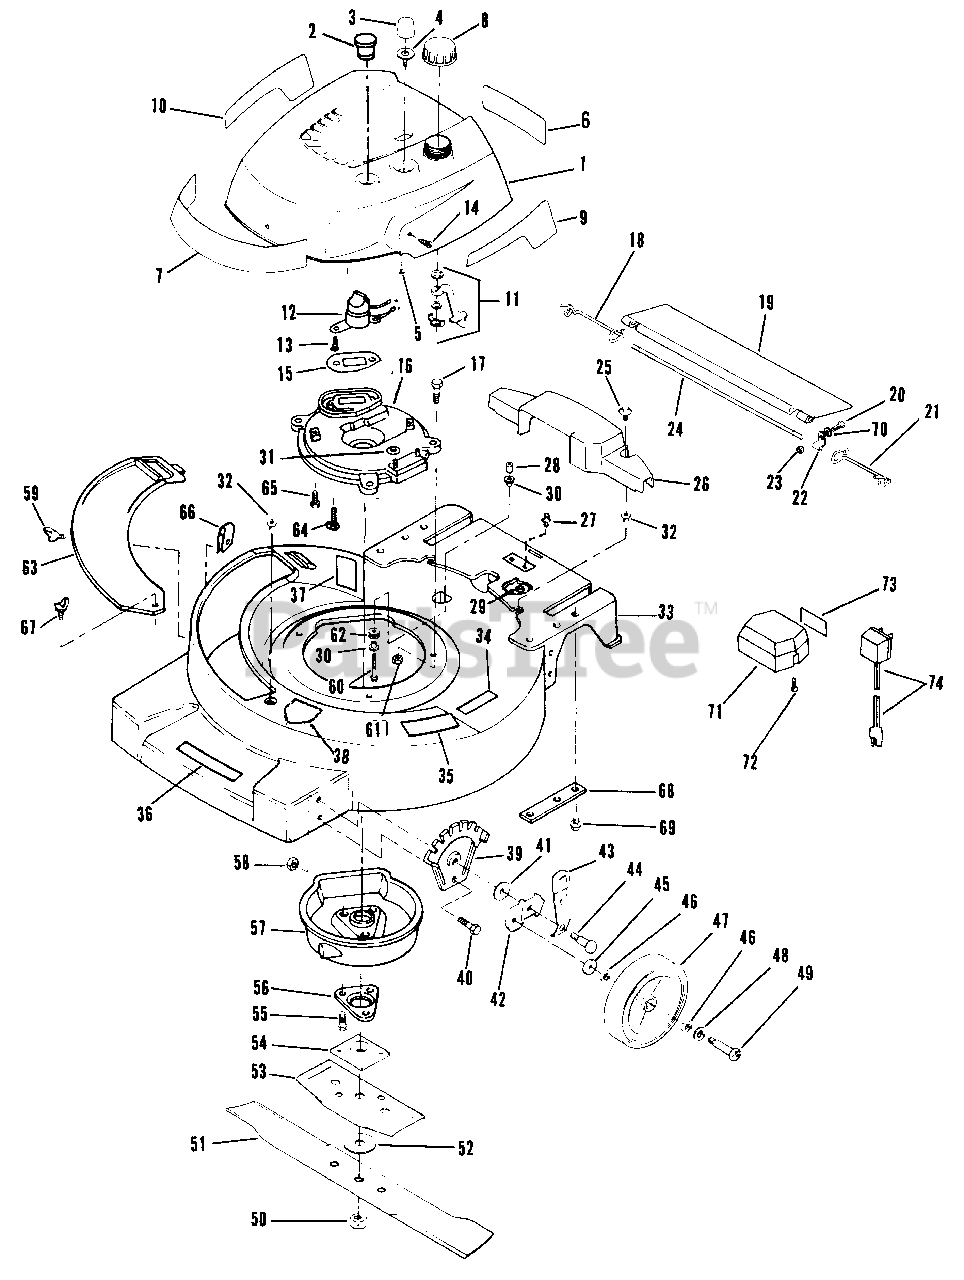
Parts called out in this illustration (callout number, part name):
1	Shroud-Engine
1	Shroud Assembly-8671AE Only
2	Plug
3	Bulb-Primer
4	Base-Primer
5	Nut
6	Decal-Instructions
7	Decal-Lawn-Boy
8	Fuel Cap
9	Decal-L.H.
10	Decal-R.H.
11	Fuel Shut-Off Assembly
12	Switch-On-Off
13	Screw
14	Screw-Shroud Mounting
15	Gasket-Exhaust
16	Plate-Muffler
17	Screw-Muffler Plate to Housing
18	Spring-R.H.
19	Shield-Trailing
20	Screw
21	Spring-L.H.
22	Clamp
23	Nut
24	Rod-Trailing Shield
25	Screw-Axle Cover Mounting
26	Cover-Drive Axle
27	Ball Stud, Battery Mounting
28	Spacer
29	Nut, Ball Stud
30	Spacer
31	Pushnut-Model Plate Mtg
32	Grommet
33	Housing Assembly
33	Housing Assembly-8671AE Only
34	Decal-Starting Pad
35	Pad-Starting
36	Decal-Caution
37	Decal-Discharge Area
38	Decal Blade Contact Warning
39	Plate-Height Adjust Backup
40	Screw-Height Adjust Plate
41	Washer
42	Bracket-Wheel Height Adjustment
43	Knob & Spring Assembly
44	Shoulder Bolt
45	Washer
46	Washer-Felt
47	Wheel-Front
48	Washer
49	Bolt-Wheel-Front
50	Nut-Blade
51	Blade-21"
52	Washer-Blade
53	Stiffener-Blade
54	Collar & Plate Assembly
55	Screw
56	Support-Crankshaft
57	Muffler Cover Assembly
58	Nut
59	Thumbscrew
60	Screw-Transmission to Housing
61	Nut-Muffler Plate to Housing
62	Grommet
63	Cover Plate
64	Screw-Muffler Plate to Block
65	Screw-Muffler Plate to Block
66	Speed Nut-Cover Plate Mounting
67	Wing Screw
68	Plate-Handle Bracket Support
69	Screw-Handle Bracket to Housing
70	Washer
71	Battery Box & Battery
72	Screw
73	Decal
74	Charger-Battery
